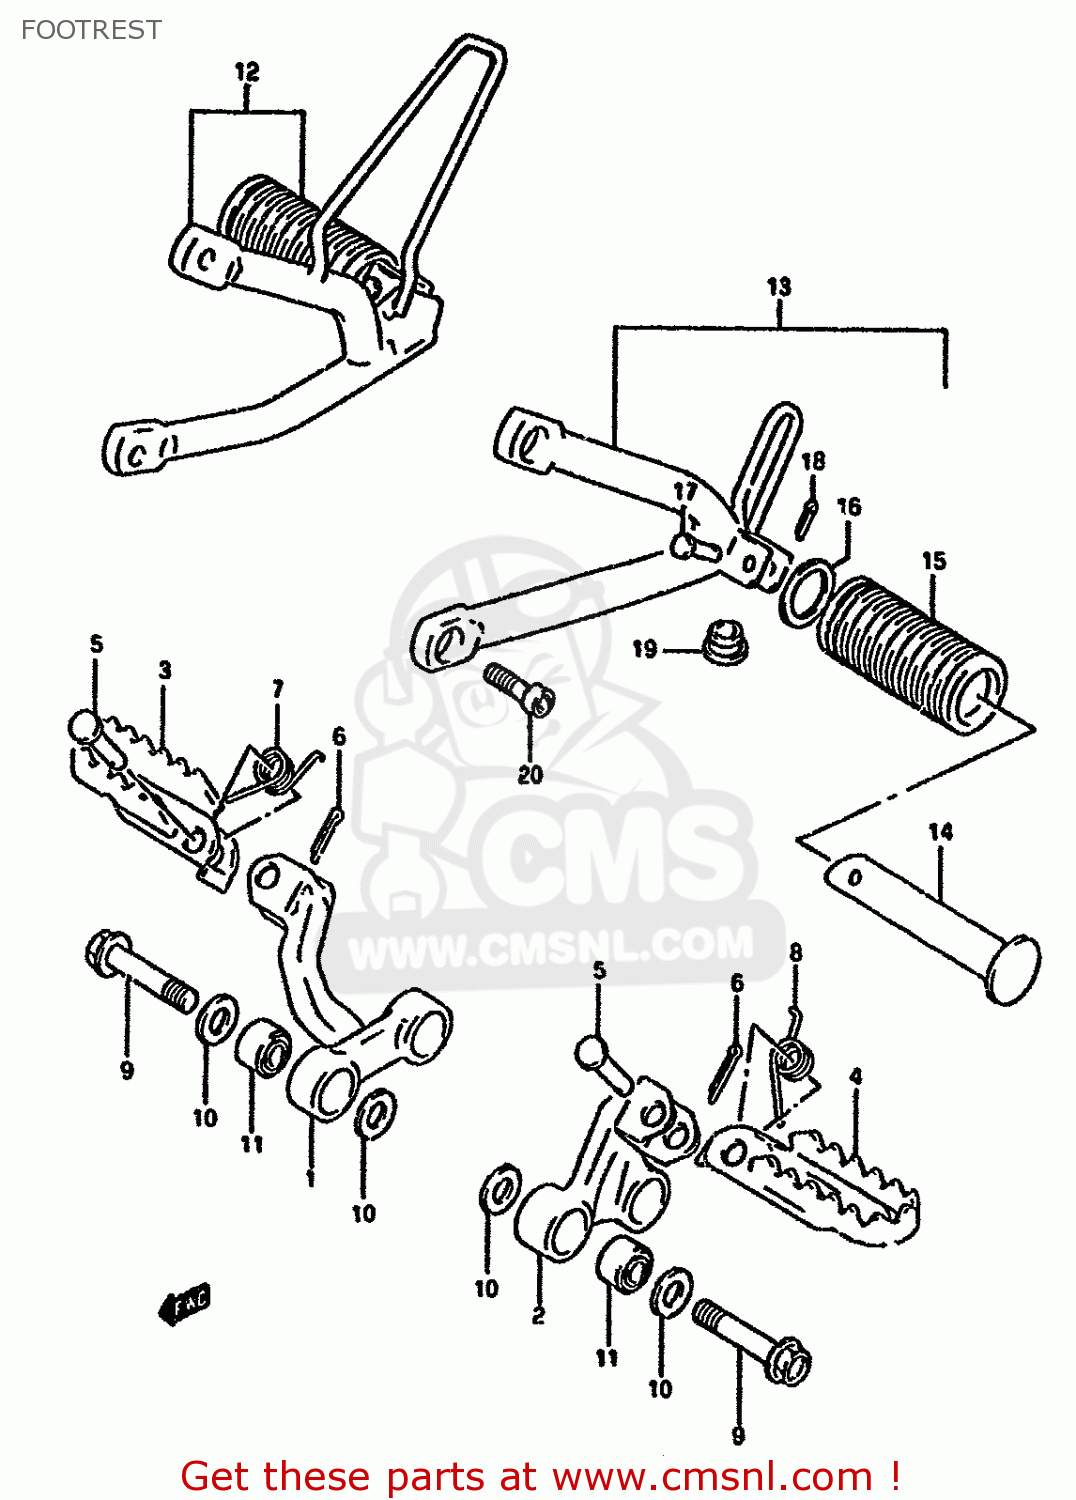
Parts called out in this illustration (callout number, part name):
1	BAR,FR FOOTREST,R
2	BAR,FRONT FOOTREST,LEFT
3	FOOTREST,FR,R
4	FOOTREST,FR,L
5	PIN
6	PIN 20X20
7	SPRING
8	SPRING
9	BOLT(10X50)
10	WASHER
11	BUSH(10.2X25X19)
12	FOOTREST ASSEMBLY,PILLION
13	FOOTREST ASSEMBLY,PILLION
14	BAR,FOOTREST RUBBER
15	RUBBER,PILLION FOOTREST
16	WASHER (19.5X32X2)
17	PIN
18	PIN
19	CAP(OD:19)
20	BOLT
